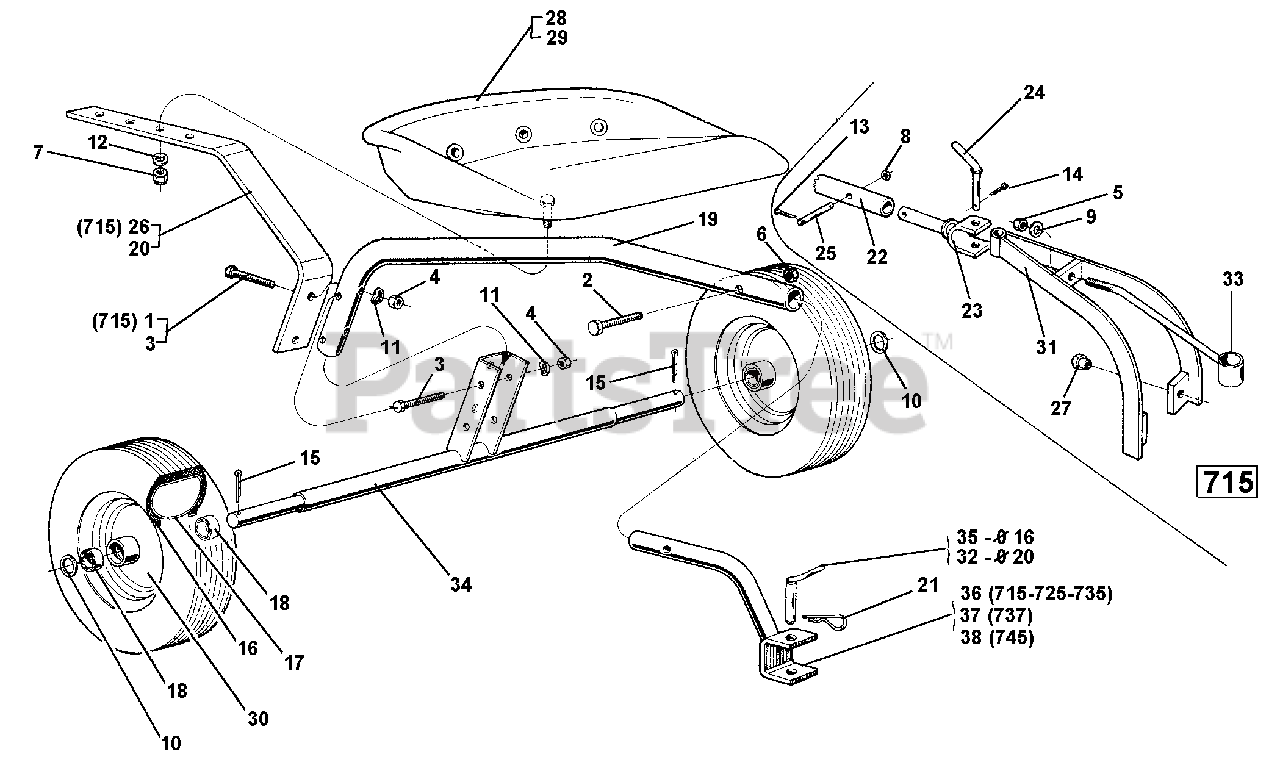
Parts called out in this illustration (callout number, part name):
1	SCREW TE M10 X 25
2	SCREW M10 X 60
3	SCREW TE M10 X 65 UNI 5739-8G
5	NUT M14 UNI 5588-5S
6	NUT, SELF LOCKING M10
7	NUT, SELF LOCKING M12
8	WASHER, FLAT 13
9	WASHER, FLAT 15
10	WASHER, FLAT 26
11	WASHER, LOCK 10.5
12	WASHER, LOCK 13
13	PIN, COTTER A 4 X 20 UNI 1336
14	PIN, COTTER A 4 X 30 UNI 1336
15	PIN, COTTER A 5 X 40 UNI 1336
16	TIRE FOR CAR 100 X 203
17	TUBE 4.00 X 8
20	SEAT SPRING
23	CONNECTION FOR CAR
26	CONNECTION FOR SEAR
27	NUT M12 X 1.25
28	PADDED SEAT
29	SEAR FOR CAR
30	SULKY WHEEL
33	TIEROD, BENT, FOR 715
36	CURVED COUPLING 725-735
37	CURVED COUPLING 737
38	CURVED COUPLING 745
